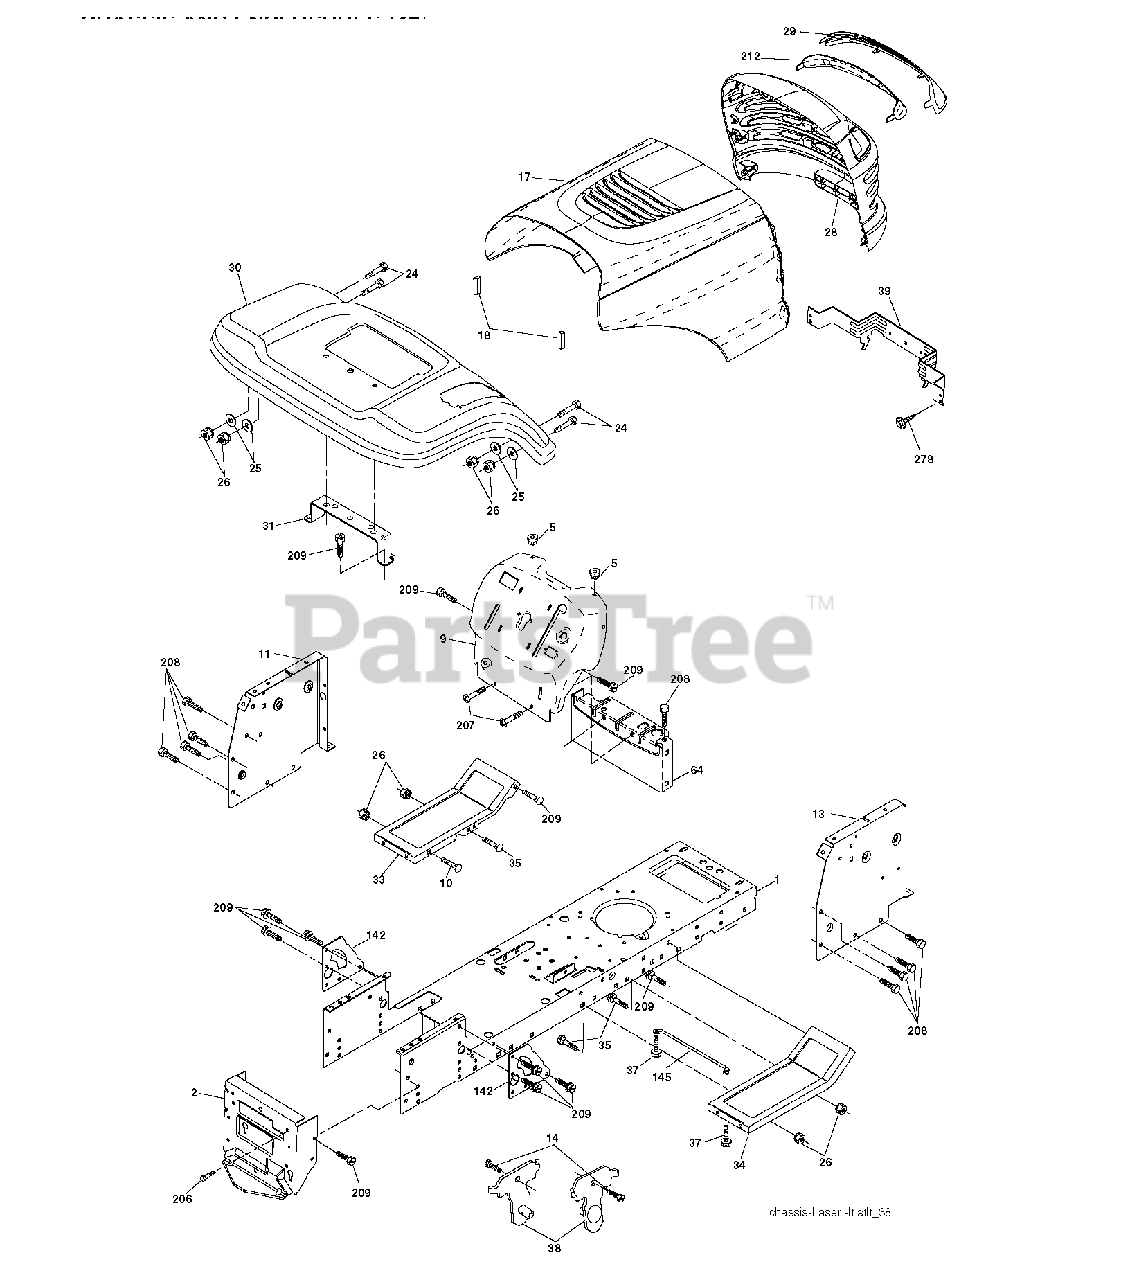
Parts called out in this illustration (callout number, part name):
1	CHASSIS STAMPING
2	DRAWBAR, 12GA
5	BUMPER.RUBBER.HOOD
10	BOLT D
11	PANEL.DASH.LH.LTX
18	BUMPER.HOOD.LARGE.1.75"
25	WASHER
26	NUT
31	BRACKET FENDER
38	BRACKET.ASM.PIVOT.MOWER.REAR
39	BRACKET PIVOT
64	DASH LOWER
142	PLATE REINFORCEMENT
145	ROD.PIVOT.HOOD
206	SHOULDER BOLT 5/16-18TT
207	SCREW, 5/16-18 X 1/2
208	SCREW 3/8-16X1/2
209	SCREW, 3/8-16X3/4
278	SCREW.#10 X 0.750.BOS THREAD
